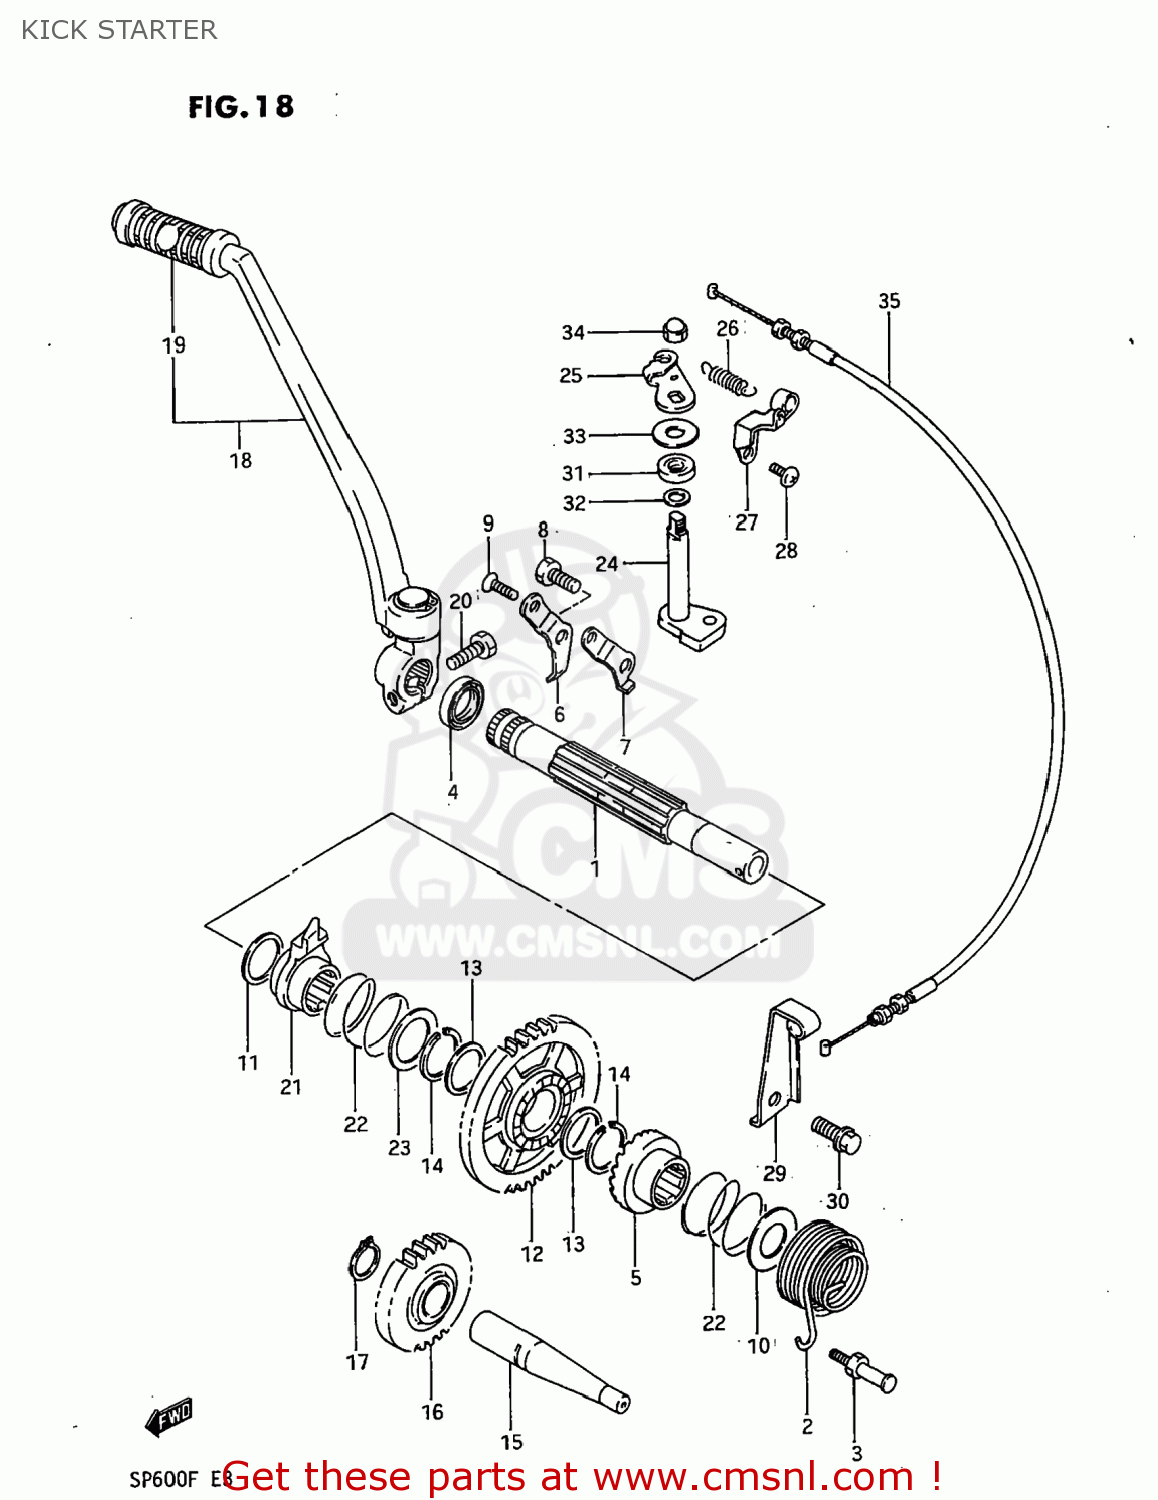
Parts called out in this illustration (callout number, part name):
1	SHAFT,KICK STARTER
2	SPRING
3	BOLT,KICK SHAFT SPRING
4	SEAL,OIL(20X27X6)
5	STARTER,KICK
6	GUIDE,KICK STARTER
7	STOPPER,KICK STARTER
8	BOLT
9	SCREW M6X1X16
10	WASHER
11	WASHER,THRUST
12	GEAR,KICK STARTER DRIVE
13	SHIM
14	CIRCLIP
15	SHAFT,KICK STARTER IDLE
16	GEAR,KICK STARTER IDLE
17	CIRCLIP
18	LEVER ASSEMBLY,KICK STARTER
19	RUBBER,KICK STARTER PEDAL
20	BOLT 8X25
21	CAM,DECOMPRESSION
22	SPRING
23	WASHER
24	SHAFT,DECOMP CAM FOLLOWER
25	ARM,DECOMPRESSION SHAFT
26	SPRING
27	HOLDER,DECOMPRESSION CABLE NO
28	SCREW
29	HOLDER,DECOMP CABLE NO.2
30	BOLT, LOWER
31	OIL SEAL
32	WASHER
33	WASHER(10.5X24X1)
34	NUT,M8X1.25X12
35	CABLE,KICK STARTER DECOMP
36	CLAMP L:35
